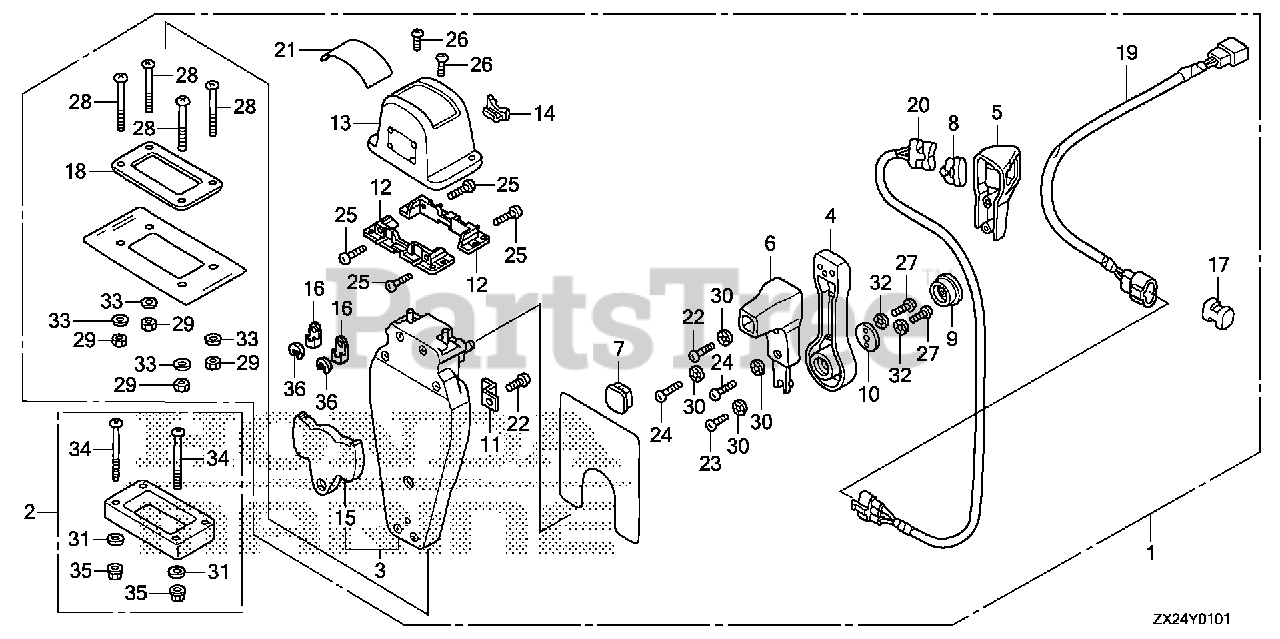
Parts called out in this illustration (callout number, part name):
1	BOX KIT, REMOTE CONTROL (TOP MOUNT SINGLE)(L)
2	SPACER KIT, REMOTE CONTROL BOX (TOP MOUNT SINGLE)
3	HOUSING ASSY., R. (INNER) (TOP MOUNT)
4	HANDLE, REMOTE CONTROL
5	COVER, R. GRIP
6	GRIP, REMOTE CONTROL HANDLE
7	CAP, GRIP
8	CAP, SWITCH
9	BUTTON, THROTTLE
10	PLATE, HANDLE
11	PLATE, CABLE CLAMP
12	BRACKET, REMOTE CONTROL HOUSING
13	HOUSING, REMOTE CONTROL BOX
14	HOUSING, LEAD
15	PLATE, DWELL
16	TERMINAL, CABLE
17	SPACER, CABLE CLAMP
18	GASKET, SINGLE
19	SUB-HARNESS ASSY., POWER TRIM-TILT (B)
20	SWITCH ASSY., POWER TRIM-TILT (B)
21	MARK, REMOTE CONTROL (SINGLE)
22	SCREW, PAN (5X16)
23	SCREW, PAN (5X10)
24	SCREW, PAN (5X20)
25	SCREW, PAN (5X18)
26	SCREW, PAN (4X10)
27	SCREW, PAN (6X18)
28	SCREW, PAN (5X40)
29	NUT, HEX. (5MM)
30	WASHER, LOCK (5MM)
31	WASHER, PLAIN (5MM)
32	WASHER, LOCK (6MM)
33	WASHER, PLAIN (5MM)
34	SCREW, PAN (5X65)
35	NUT, HEX. (5MM)
36	E-RING (6MM)
